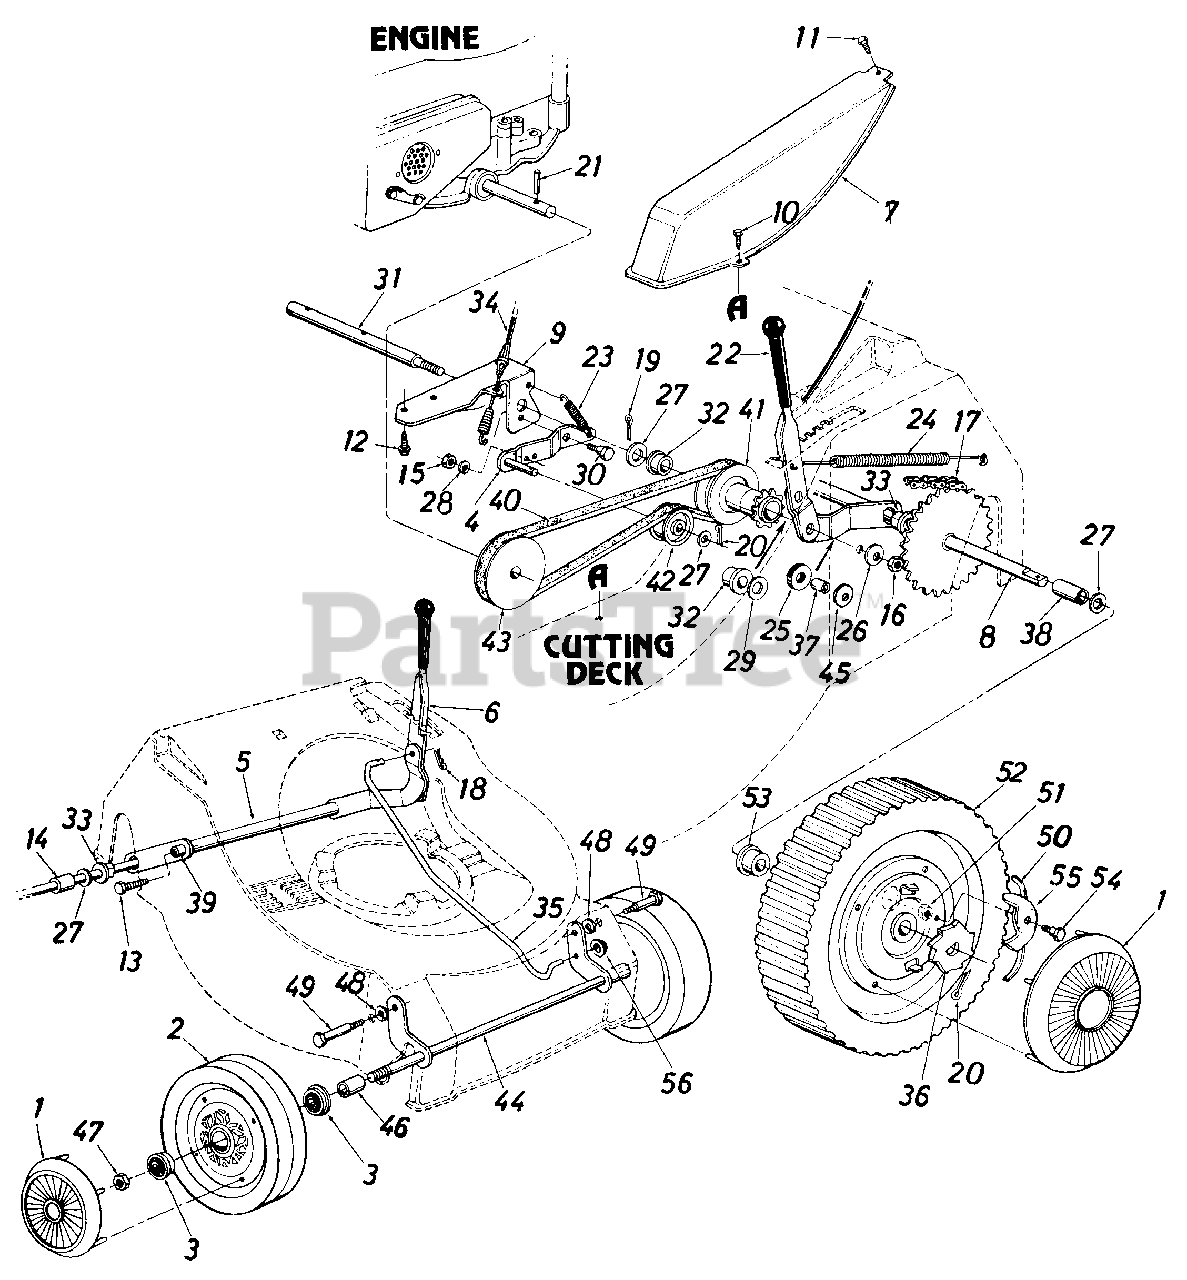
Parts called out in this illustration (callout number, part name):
1	Hub Cap
2	Wheel Ass'y. Comp. 8 x 1. 75-Front
3	Flanged Ball Brg. .500" I.D.
4	Idler Brk't. Ass'y.
5	Axle Ass'y.
6	Height Adj. Handle
7	Belt Cover
8	Rear Shaft Ass'y.
9	Bracket-Pulley Shaft
10	Hex B-Tap Scr. 1/4 x .38" Lg.
11	Hex Drilling Scr. #10 x .50" Lg.
12	Hex Wash. Hd. B-Tap Scr. 5/16-18 x .50" Lg.
13	Hex Wash. Hd. TT-Tap Scr. 3/8-16 x 1.00" Lg.
14	Spacer .526" I.D. x .690" O.D. x .640" Lg.
15	Hex Nut 1/4-20 Thd.*
16	Hex Jam Nut 3/8-16 Thd.
17	#48 Chain 1/2" Pitch x 34 Links-E.
18	Intern. Cot. Pin 5/16" Dia.
19	Cotter Pin 3/32" Dia. x 1.00" Lg.*
20	Cot Pin 1/8" Dia. x 1.00" Lg.*
21	Spring Pin Spir. 3116" Dia. x 1.50" Lg.
22	Grip-Black
23	Extension Spring .33" O.D. x 1.12" Lg.
24	Extension Spring .50" O.D. x 4.25" Lg.
25	Rubber Wash.
26	Bell-Wash. .400" I.D. x .88" O.D.
27	Fl-Wash. .531" I.D. x .930" O.D.
28	L-Wash. 1/4" I.D.*
29	Fl-Wash. .390" I.D. x 1.00" O.D.
30	Shld. Bolt .375" Dia. x .181
31	Pulley Shaft .500" Dia.
32	Flange Brg. .506" I.D. Plastic
33	Hex Flange Brg. x .506" I.D. Plastic
34	Self-Propelled Clutch Cable-50.0" Lg.
35	Linkage Rod .38" Dia.
36	Ratchet Wheel
37	Spacer .395" I.D. x .503" O.D. x .562" Lg.
38	Spacer .75" I.D. x .88" O.D. x 1.41 " Lg.
39	Spacer .385" I.D. x .503" O.D. x.270" Lg.
40	"V"-Belt 1/2" x 33" Lg.
41	Pulley w/9 Tooth Sprocket Ass'y.
42	Flat Idler Plastic 1.62" Dia.
43	"V"-Pulley .50" I.D. x 2.52" O.D.
44	Front Axle Ass'y.
45	Belleville Washer .40" I.D. x 1.13" O.D.
46	Sleeve .526" I.D. x .690" O.D. x .880 Lg.
47	Hex Ins. L-Nut 1/2-20 Thd.
48	Int. L-Wash. 3/8" I.D.
49	Shld. Bolt .625 Dia. x .425
50	Spring-Nylon
51	Hex Ins. L-Nut 1/4-20 Thd.
52	Wheel Ass'y. Comp. 9.25 x 1.75 Rear
53	Flanged Ball Brg. .500" I.D.
54	Shoulder Bolt .342" Dia. x .268
55	Pawl
56	Cap Speed Nut 5/16" Rod
